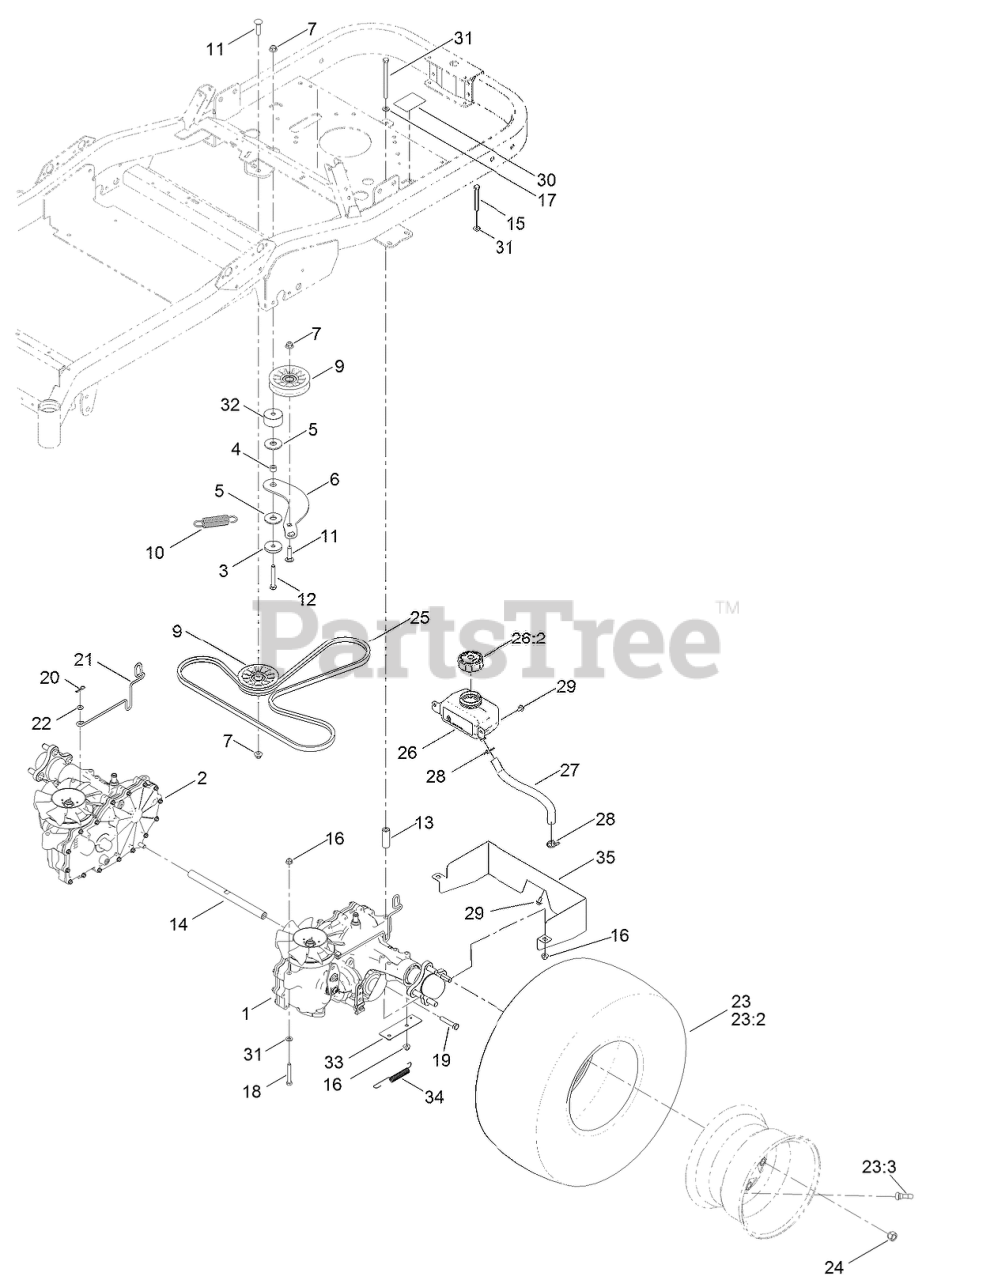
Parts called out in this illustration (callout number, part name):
1	LH HYDRO TRANSMISSION ASM
2	RH HYDRO TRANSMISSION ASM
3	WASHER-PLAIN
4	SPACER
5	WASHER-FRICTION, COMPOSITE
6	ARM-IDLER
7	NUT-HF, NI
9	PULLEY-IDLER, FLAT
10	SPRING-EXTENSION
11	SCREW-CARR
12	SCREW-HH
13	SPACER-HYDRO
14	SHAFT-CROSS, HYDRO
15	SCREW-HH
16	NUT-HF, NI
17	SCREW-HH
18	SCREW-HH
19	SCREW-HH
20	PIN-COTTER
21	ROD-BYPASS
22	WASHER
23	TIRE AND WHEEL ASM
23:3	STEM-VALVE
24	NUT-LUG
25	V-BELT
26	HYD RESERVIOR ASM
26:2	CAP-RESERVOIR, HYD
27	HOSE-OVERFLOW
28	CLAMP-HOSE
29	SCREW-HHFTF
30	DECAL-BYPASS
31	WASHER-PLAIN
32	SPACER
33	PLATE-SPRING
34	SPRING-EXTENSION
35	Guard, Rear
